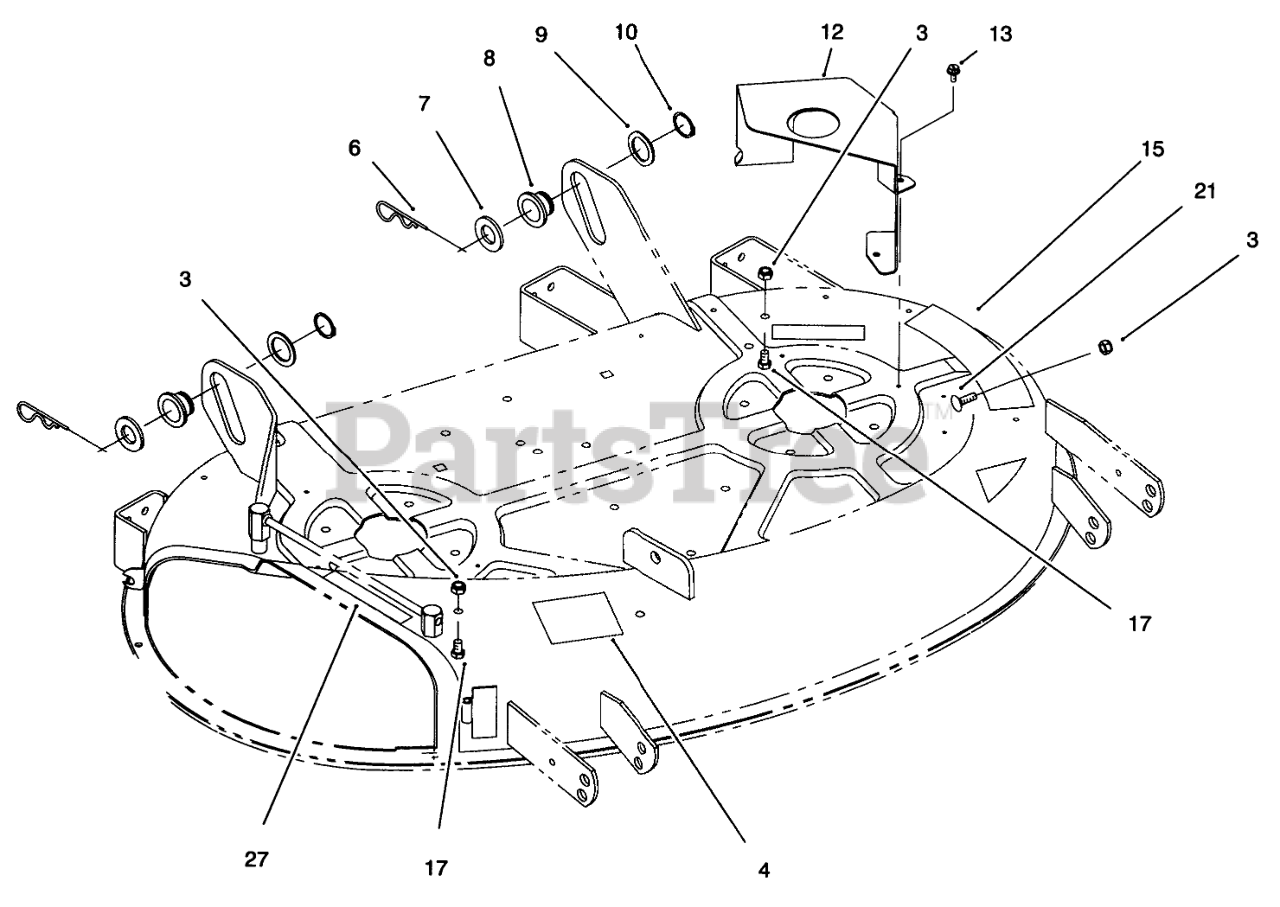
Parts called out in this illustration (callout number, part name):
3	NUT-LOCK, NI
4	DECAL-ROUTING, BELT
6	PIN-HAIR
7	WASHER-FLAT
8	ROLLER-LIFT
9	WASHER
10	RING-RETAINING
12	COVER-BELT
13	SCREW-HWHTF
15	DECAL - DANGER
17	SCREW-HH
21	SCREW-HH
27	DECAL-DANGER
